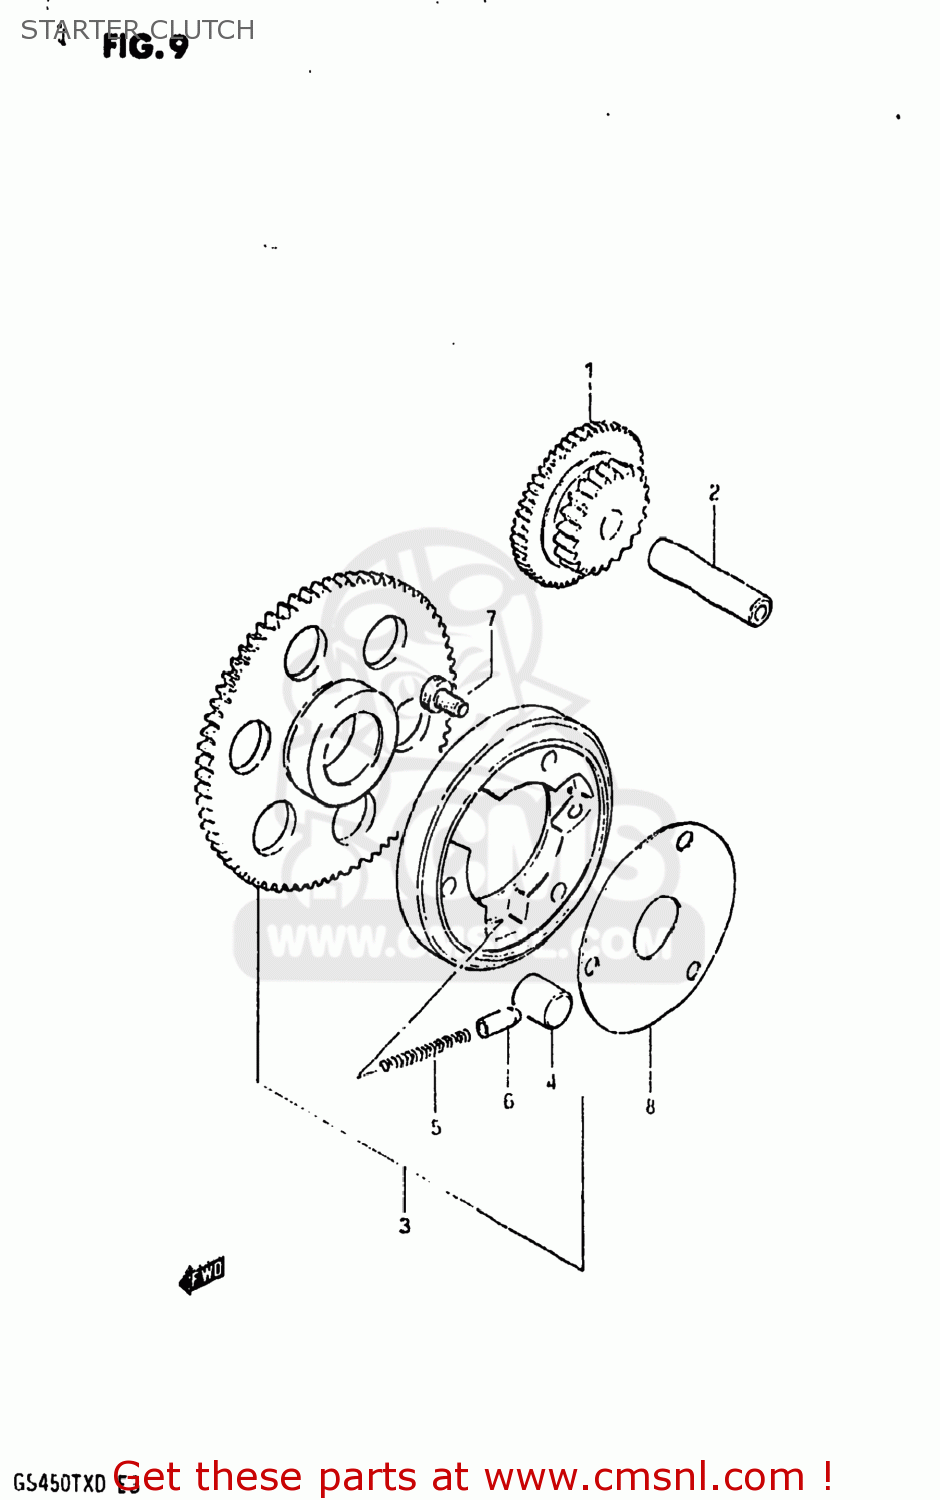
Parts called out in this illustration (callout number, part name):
1	GEAR,STARTER IDLE
2	PIN(7.4X13X56)
3	CLUTCH SET,STARTER
4	ROLLER(15X13)
5	SPRING
6	PIECE,PUSH
7	BOLT
8	SHIM,STARTER CLUTCH HUB
